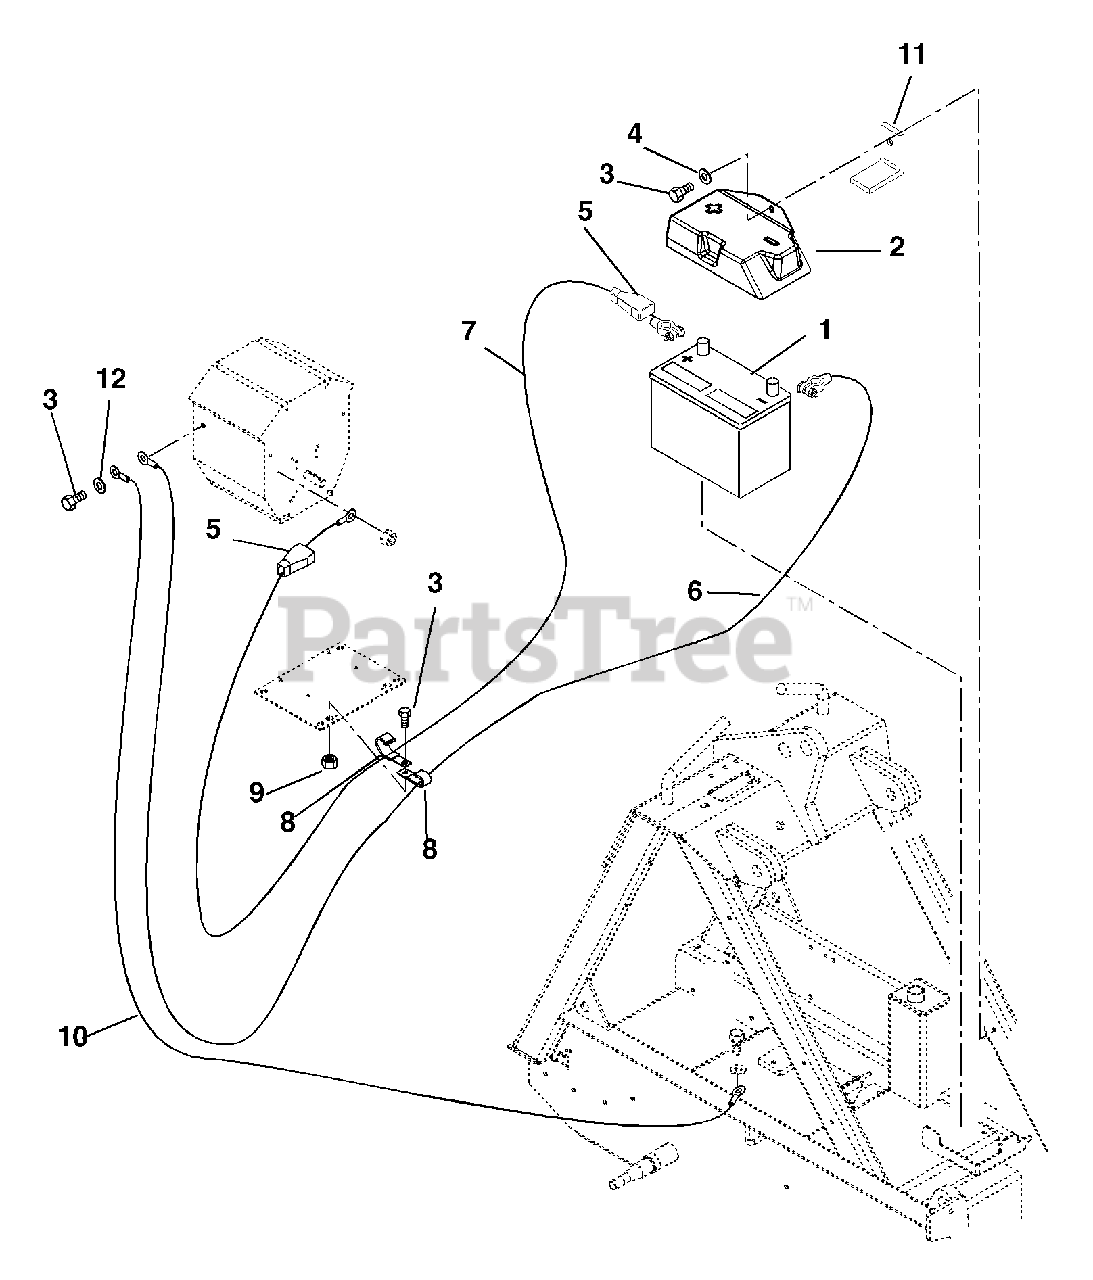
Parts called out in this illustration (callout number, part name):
2	Cover-Battery
3	Bolt-Hex M8 x 1.25 x 16
4	Washer-Flat-Steel .344 x .688 x .065
5	Cover,Battery Terminal
6	Cable-Battery Positive
7	Cable-Battery Negative
8	J-Clamp
9	Nut-Locking-Nylon M8-1.25
10	Wire-Ground
11	Bracket, Battery Holddown
12	Washer-Locking .31 x .078 Regular
